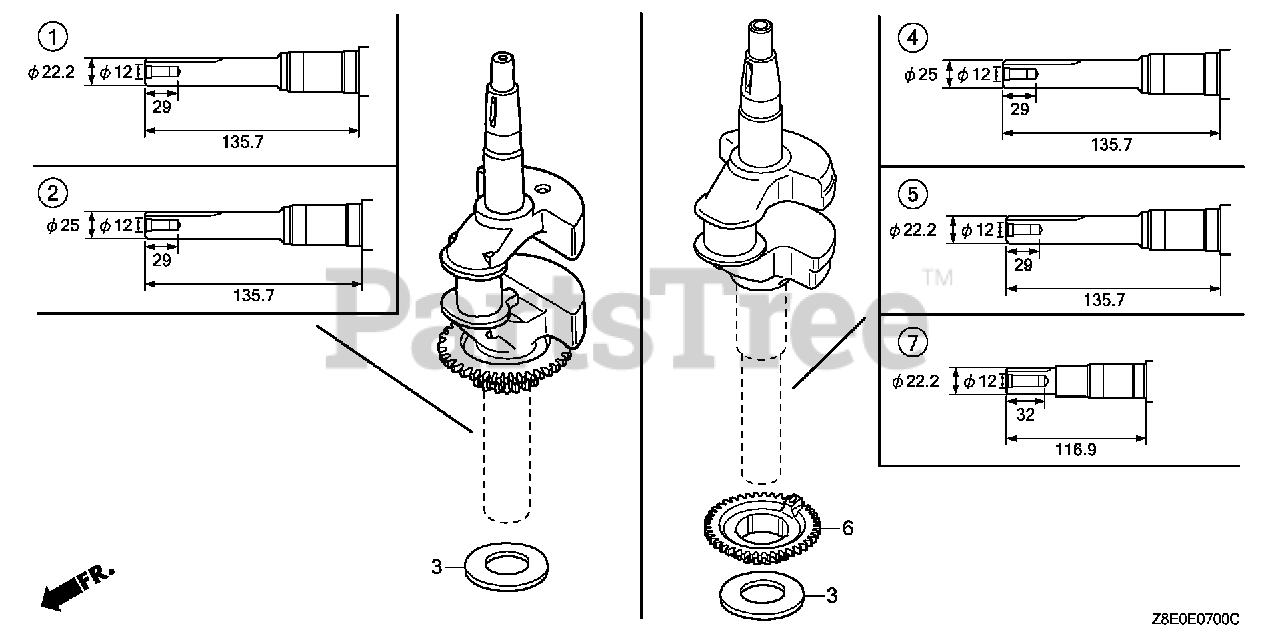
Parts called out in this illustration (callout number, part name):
3	WASHER, THRUST
6	PULLEY, TIMING BELT DRIVE
7	CRANKSHAFT
